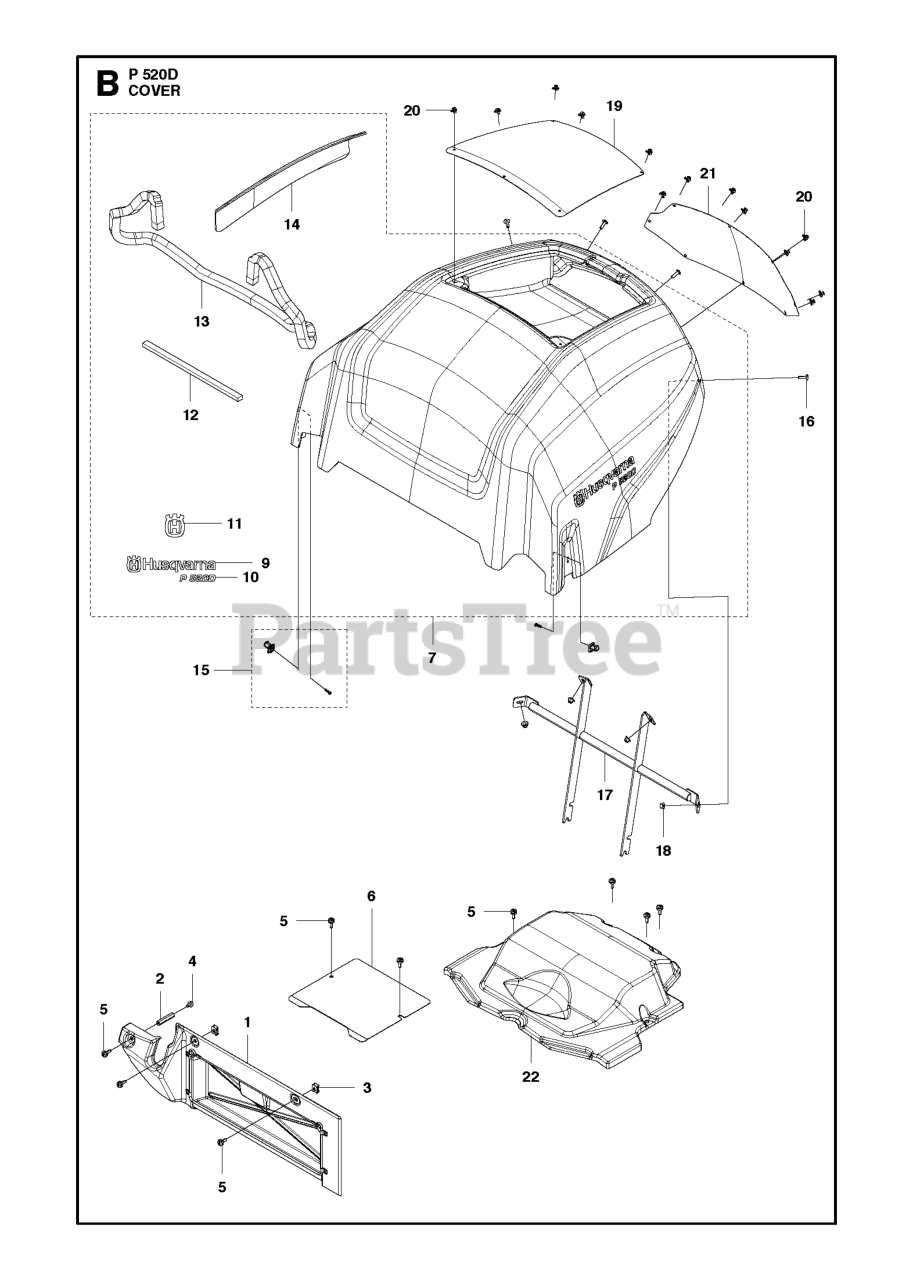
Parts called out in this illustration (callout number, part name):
9	DECAL.HUSQVARNA.210MM
11	DECAL HUSQVARNA CROWN HEIGHT 5
18	NUT FLANGE
